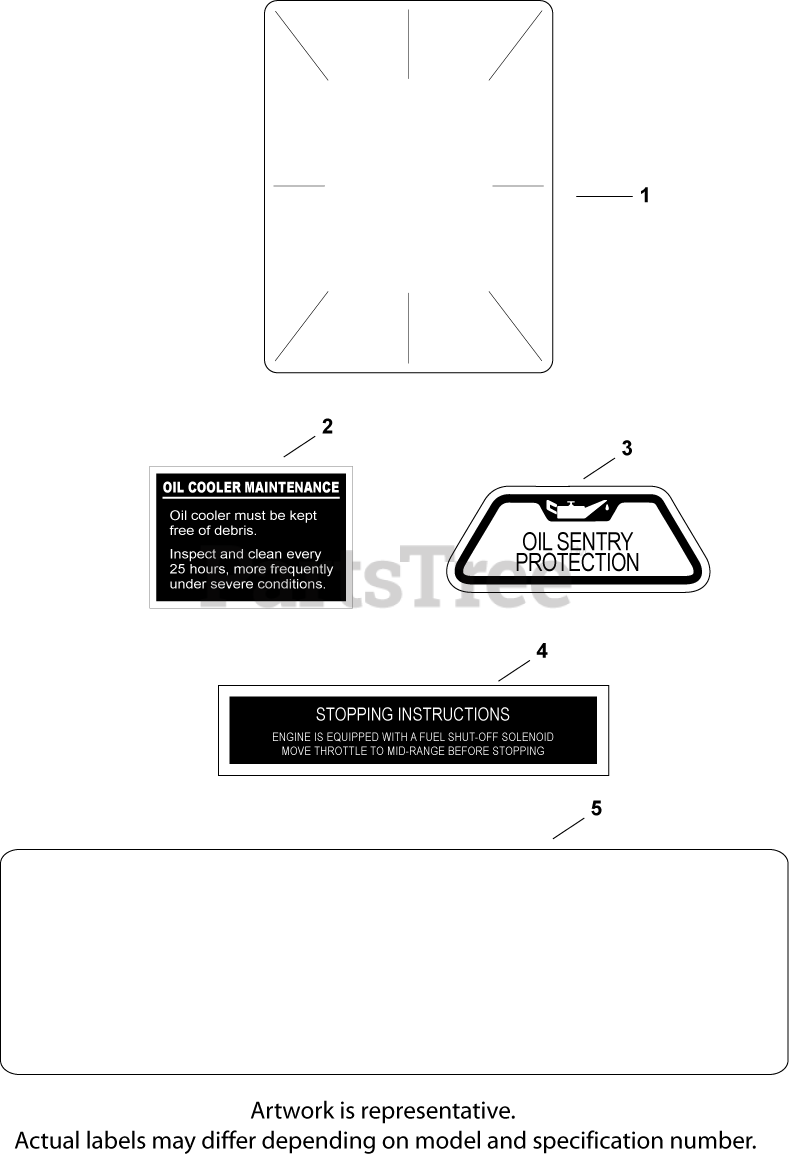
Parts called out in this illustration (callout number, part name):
1	DECAL, CLEAR LAMINATE USE 25 113 70-S
2	DECAL, OIL COOLER - (#DSC)
3	DECAL, OIL SENTRY - (#DSC)
4	DECAL, STOPPING INSTRUCTION
5	DECAL, 18 HP
